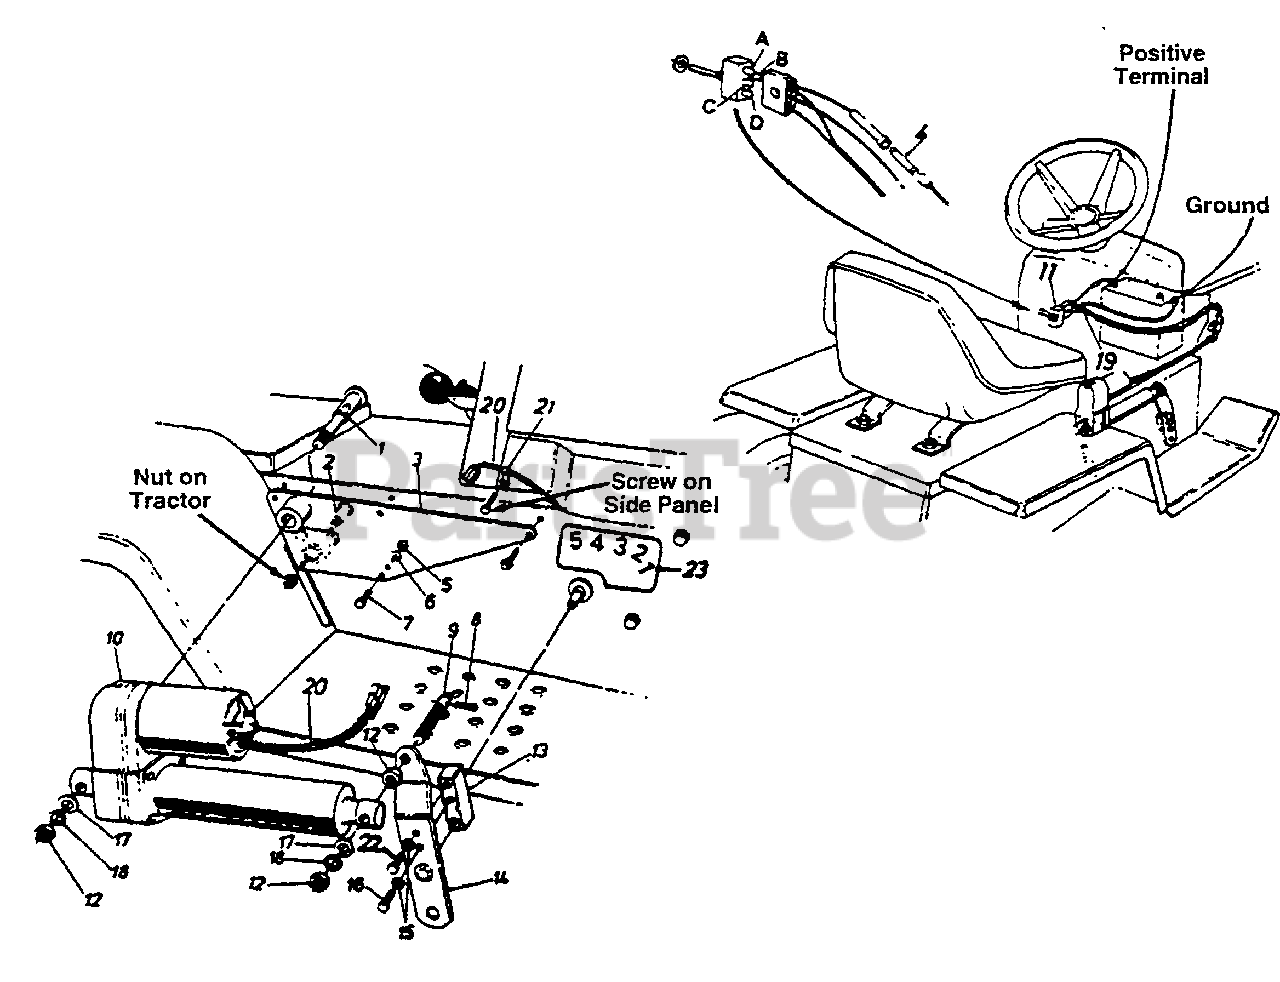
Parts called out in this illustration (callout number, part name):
1	Pivot Pin
2	Shld. Bolt .626" Dia. x .96"
5	Hex Nut 1/4-28 Thd.
6	L-Wash. 1/4" I.D.
7	Hex Bolt 1/4-28 x .75" Lg. (Grade 5)
8	Cotter pin
9	Indicator & Mtg. Pin
10	Electric Actuator
11	Toggle Switch
12	Hex Jam Nut 1/2-13 Thd.
13	Lift Shaft Drive
16	Hex Bolt 5/16-24 x 1.0" Lg. (Grade 5)
17	Fl-Wash .53" I.D. x .93" O.D.
18	L-Wash. 1/2" I.D.
19	Wire Harness
20	Plastic Tubing - 7"
21	Clamp
22	Hex Bolt 5/16-18 x 1" Lg. (Grade 5)
23	Label
A	Blue Wire Connects to Positive Terminal on Battery
B	Yellow Wire Connects to Actuator
C	Black Wire Connects - To Frame
D	Red Wire Connects tp Actuator
